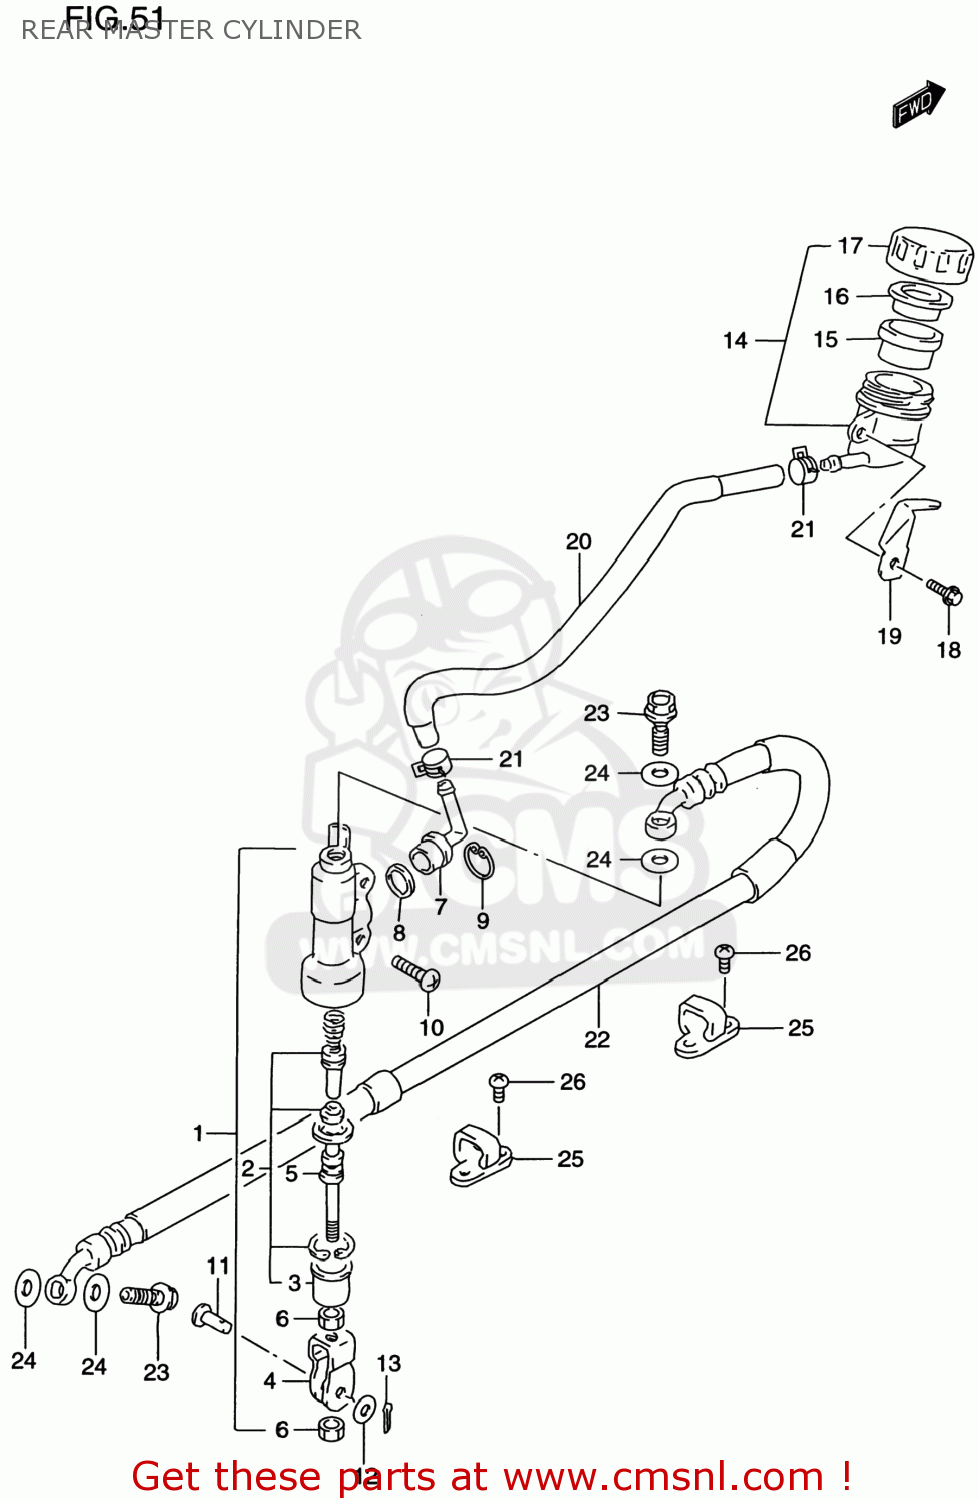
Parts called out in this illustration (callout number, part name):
1	CYLINDER ASSY,RR MASTER
2	PISTON/CUP SET
3	BOOT
4	YOKE
5	ROD,PUSH
6	NUT
7	CONNECTOR
8	O RING
9	CIRCLIP
10	SCREW(6X16)
11	PIN(8X20)
12	WASHER(8.5X13X1.6)
13	PIN 20X15
14	TANK ASSY,RR BRAKE RESERVOIR
15	DIAPHRAGM
16	PLATE
17	CAP
18	BOLT
19	GUARD,RSVR TANK CAP
20	HOSE,RESERVOIR TANK
21	CLIP
22	HOSE COMP,REAR BRAKE
23	BOLT UNION
24	WASHER(10X15X1.5)
25	GUIDE,RR BRAKE
26	SCREW
